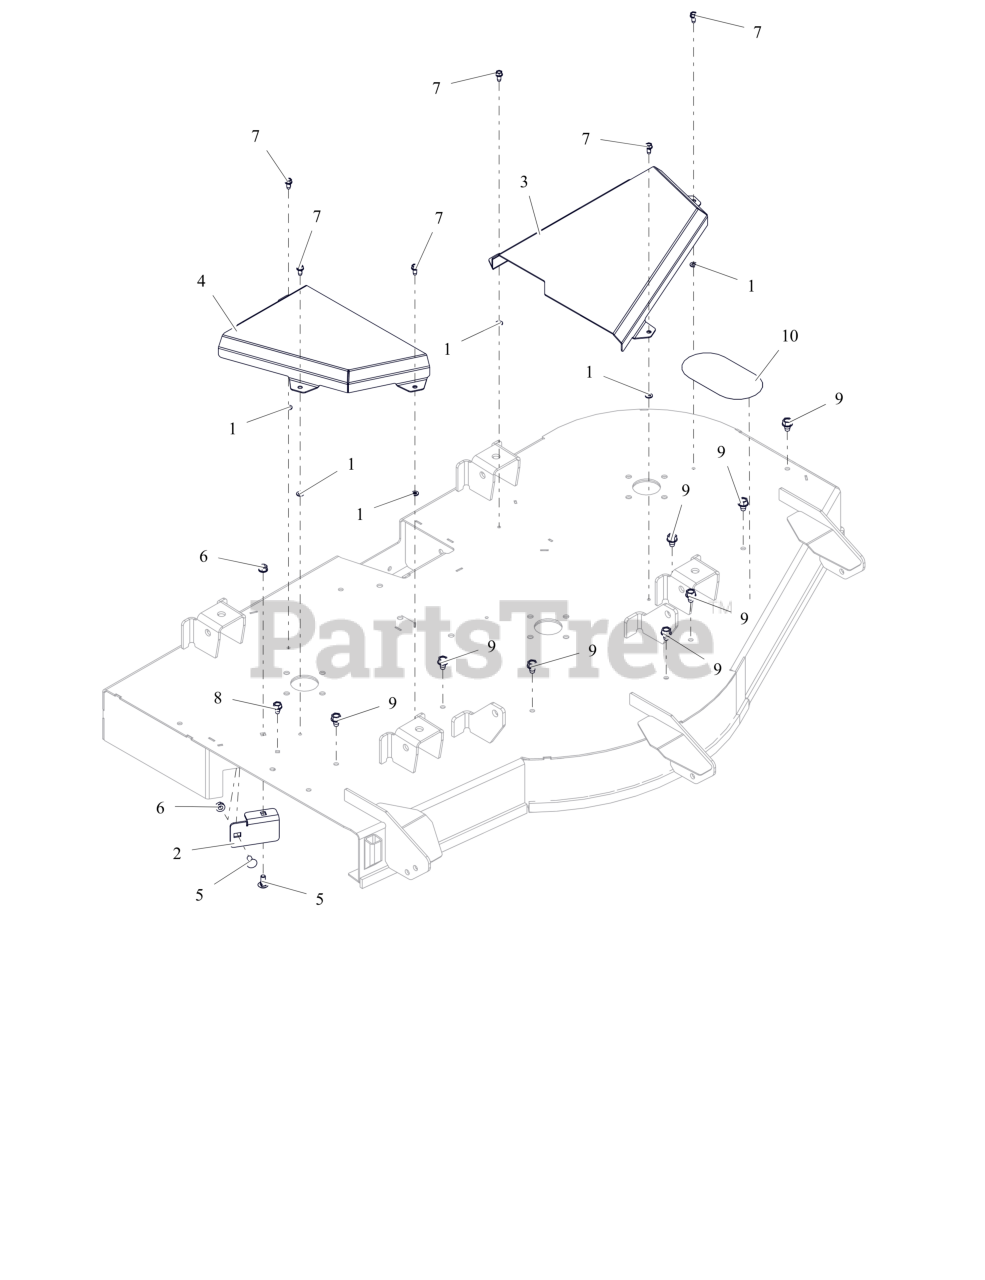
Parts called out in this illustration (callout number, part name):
1	WASHER- .257X.500 X .062 NYLON
2	STRIP- DEFLETOR - 52"
3	COVER- LH BELT - 52"
4	COVER- RH BELT - 52"
5	BLT,RHSN .31-18X.75 G5 ZCC
6	NUT-LK-TOP-FLG .312-18 GF ZCC
7	SCR-TAP .25-20X.50 HWH ZCC
8	SCR,TAP .312-18X.50 HWH TR ZCC
9	SCR,TAP .375-16X.50 HWH TR ZCC
10	TAPE- GRIP - IKON LIMITED
